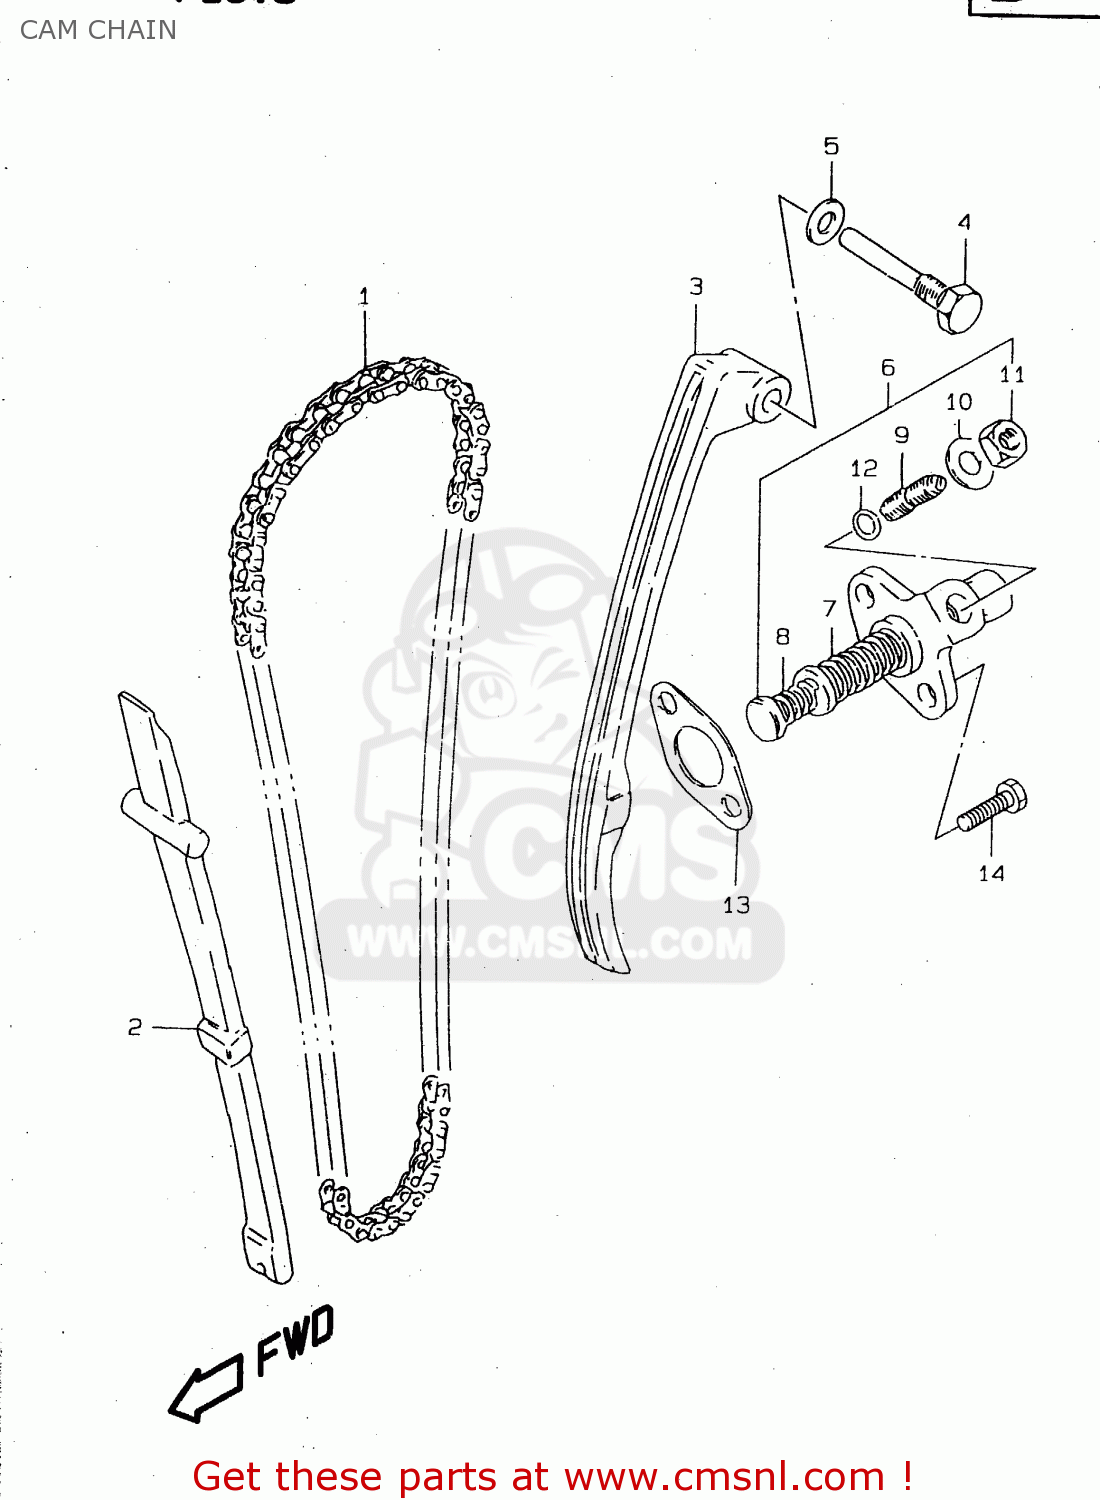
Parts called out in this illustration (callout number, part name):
1	CHAIN,CAMSHAFT DRIVE
2	GUIDE,CAM CHAIN
3	TENSIONER,CAM CHAIN
4	BOLT,CAM CHAIN TENSIONER
5	GASKET 8.2X14X1 (NAS)
6	ADJUSTER ASSEMBLY,TENSIONER
7	SPRING
8	SPRING
9	SCREW
10	WASHER
11	NUT
12	O RING(D:1.9,ID:5.7)
13	GASKET,TENSIONER ADJUSTER (NAS)
14	BOLT
